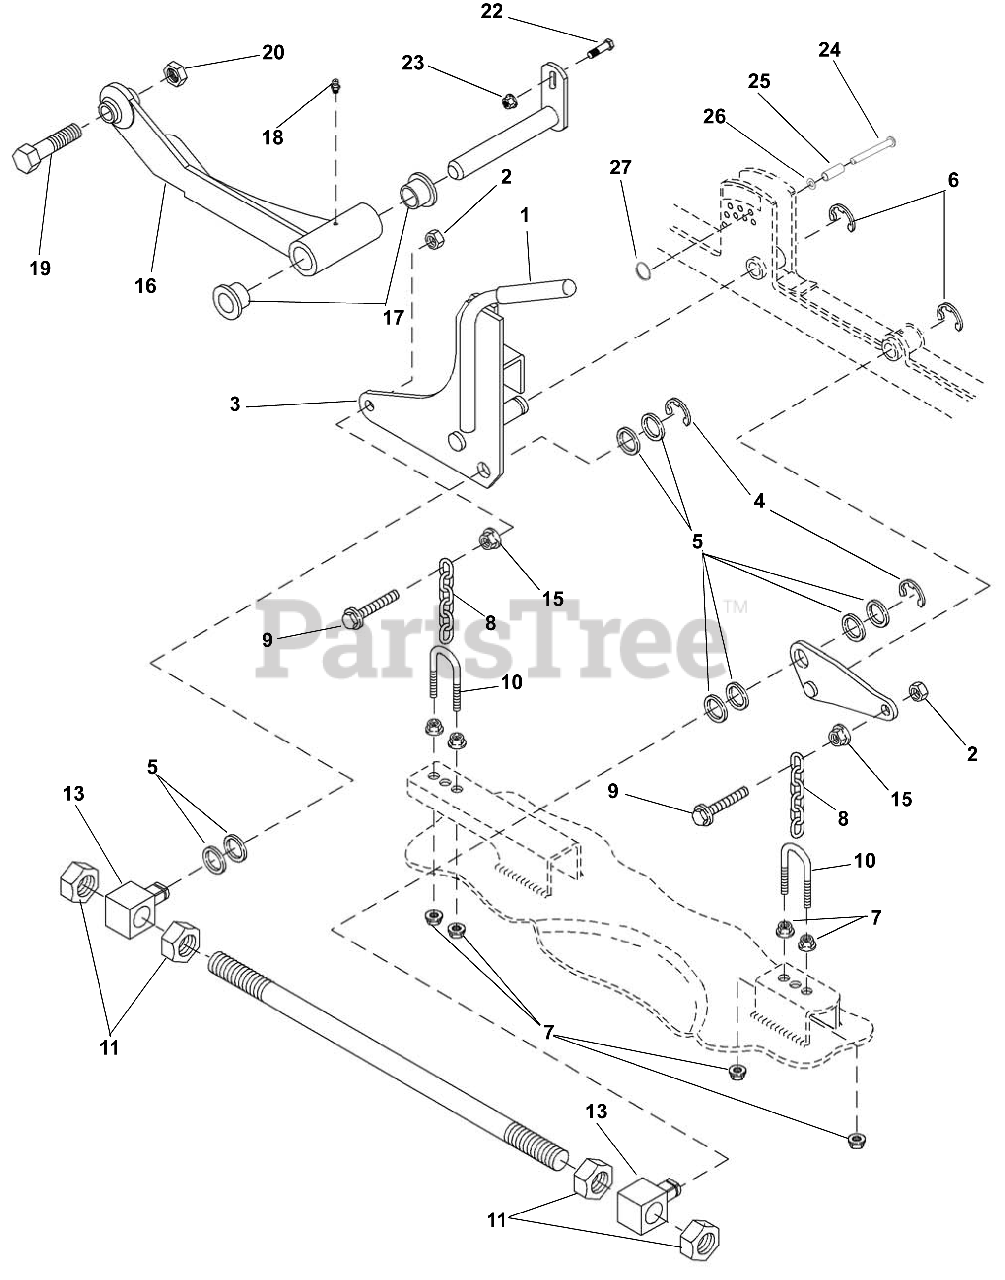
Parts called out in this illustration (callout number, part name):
1	GRIP
2	LOCKNUT, M10X1.50 WHIZ GR10 Y
3	LIFT ARM, LH REAR
3	LIFT ARM, RH REAR
4	SNAP RING
5	WASHER,JDS24-.891X1.375X.048-S
6	SNAP RING
7	@NUT-SPNLK-FLG .375-16 YWZC
8	CHAIN, DECK LIFT
9	BLT M10 X 1.5X40 YWZC
11	NUT-HEX .75-10 YWZC
12	ROD, DECK LIFT
13	SWIVEL
14	LIFT ARM, LH FRONT
14	LIFT ARM, RH FRONT
15	LOCKNUT, M10X1.50 WHIZ GR10 Y
16	THRUST ARM, LH, 48" DECK
16	THRUST ARM, RH, 48" DECK
17	BUSHING
18	FITTING, LUBRICATION
19	BLT-HEX .75-10X3.00 GR5 YWZC
20	NUT-HEX .75-10 YWZC
21	PIVOT PIN, THRUST ARM
22	@BLT-RDHDSQNK .25-20X1.00 G5YZ
23	@NUT-LK-NYL M8-1.25 YWZC
24	PIN, CLEVIS
25	BUSHING
26	PUSHNUT, M12 BOLT RETAINER
27	RING, LOCKING
